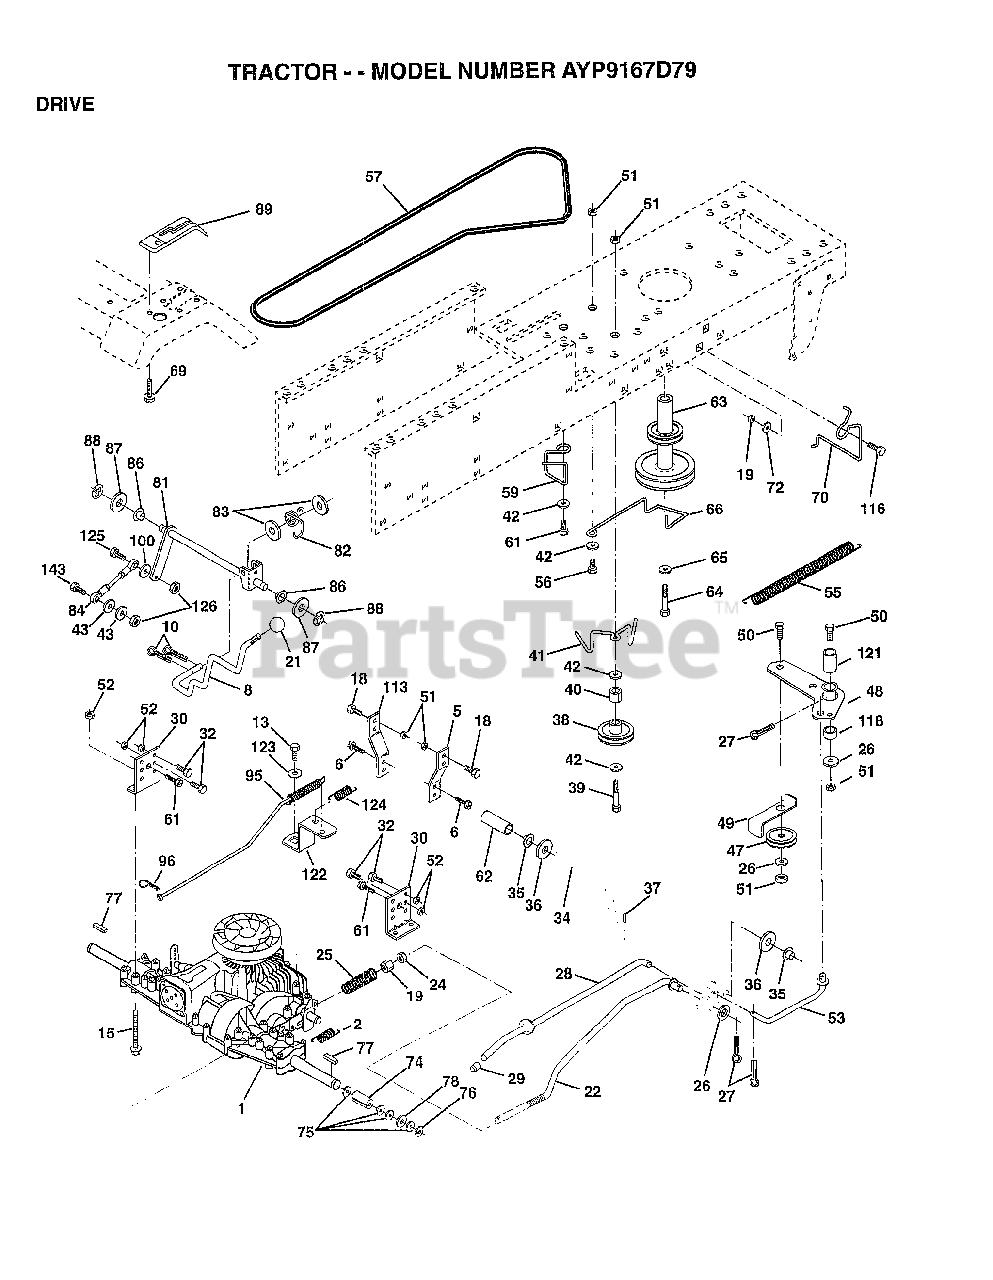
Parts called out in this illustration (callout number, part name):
2	SPRING.BRAKE.RETU
6	SCREW
8	ROD SHIFT FEND YT
10	PIN COTTER 1/8
13	BOLT.1/4-28.W/PAT
15	BOLT.HX.FLG.5/16
18	BOLT
19	NUT
21	KNOB T (1/2-HOLE)
22	BRAKE ROD
24	NUT
25	SPRING ROD LT
26	WASHER
27	COTTER PIN
28	ROD.BRAKE.PARK.LT
30	TRANSAXLE MTG BKT
32	BOLT
34	SHAFT ASM-PEDAL F
35	NYLON BEARING
36	WASHER LT
38	PULLEY.IDLER.FLAT
39	BOLT
40	SPACER T
42	WASHER
43	WASHER T
48	BELLCRANK ASM
49	RETAIN BELT
53	"LINK, CLUTCH T"
55	"SPRING, RETURN LT"
57	"V-BELT,GRD DRIVE"
59	KEEPER BELT CNTSP
61	SCREW
62	PEDAL COVER T
63	PULLEY.ENGINE
64	BOLT
65	LOCKWASHER
66	KEEPER-BELT
69	SCREW HEXWSH H-L
70	KEEPER BELT ENG
72	WASHER
75	WASHER
76	E-RING LT
77	SQUARE KEY
78	WASHER
81	SHAFT ASM CROSS
82	"SPRING,TORSION"
83	WASHER
84	"ROD TIE, PVST 20"""
86	BUSHING
87	WASHER D
88	KLIP RING
95	ROAD ASM BYPASS
100	WASHER M
113	"STRAP,TORQUE"
116	BOLT RDHD 3/8-16
118	SPACER-BELLCRANK
121	NYLINER-CLUTCHING
122	"PLATE-BYPASS,PVST"
123	WASHER
124	SPRING RETURN
143	BOLT
